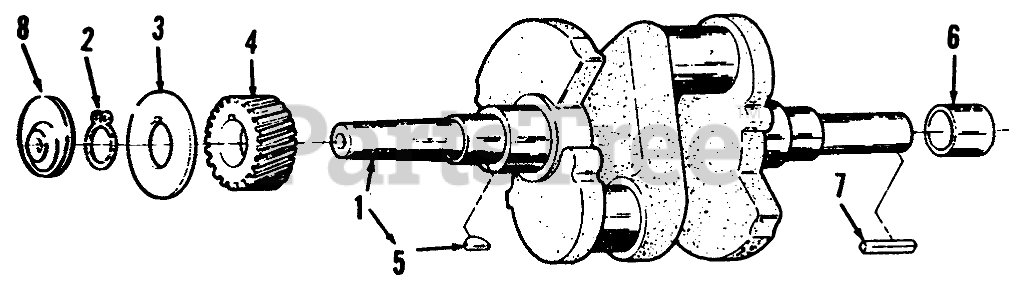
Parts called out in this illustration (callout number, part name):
1	CRANKSHAFT
3	Washer
4	Gear
5	Key
7	Key
